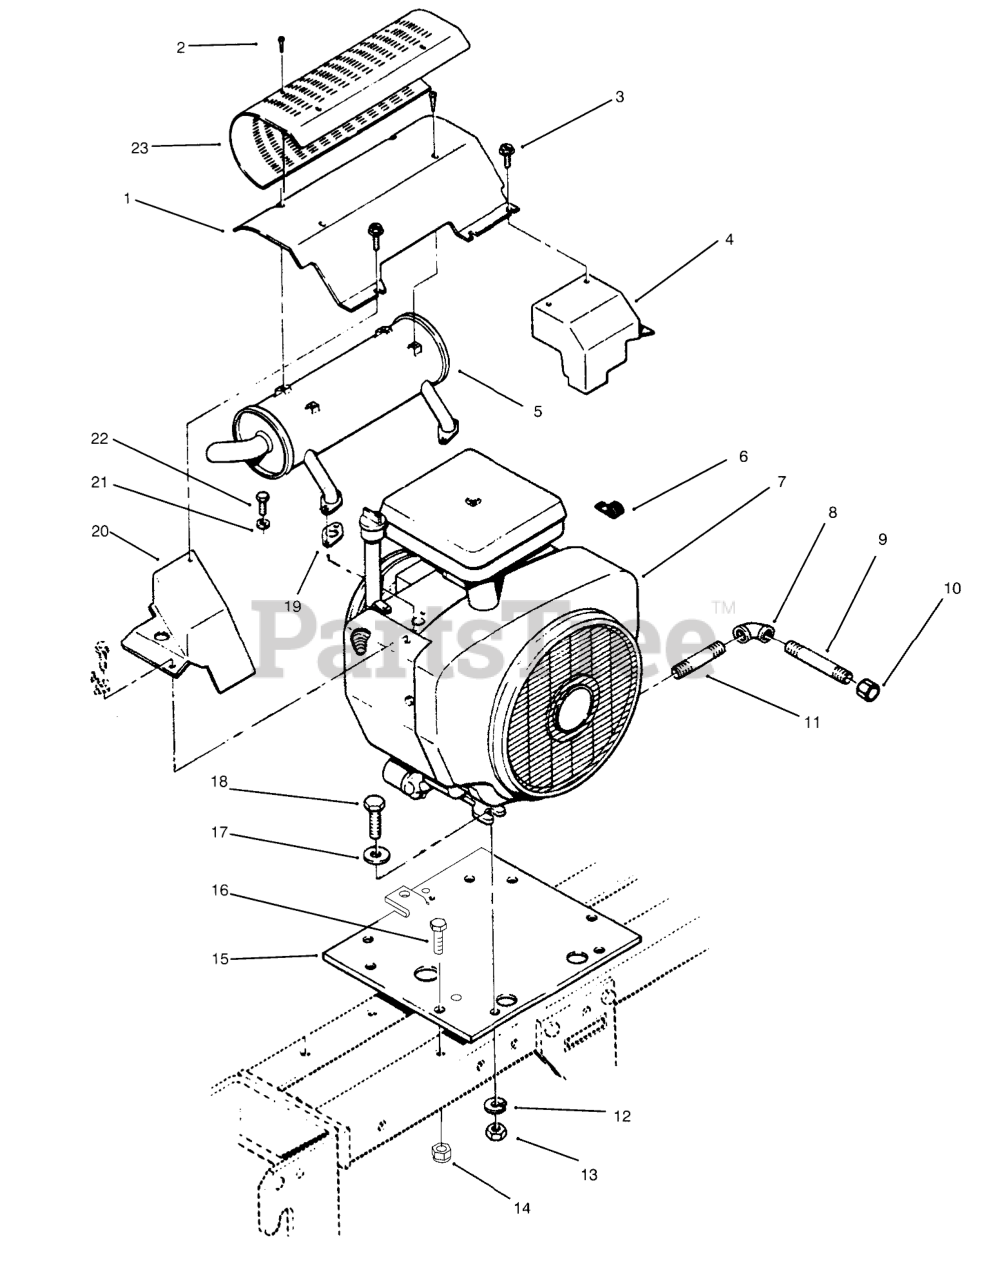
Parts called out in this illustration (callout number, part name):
1	Air Deflector
2	SCW 10-24 STAINLESS
3	SCREW
4	RH Exhaust Cover
5	MUFFLER-EXHAUST
6	CLIP
7	Engine-20HP
8	ELBOW 3/8 90 DEG
9	PIPE-NIPPLE 3/8 X 4"
10	CAP-PIPE
11	Pipe
12	WASHER-LOCK
13	NUT-HEX
14	NUT-LOCK, NI
15	PLATE-ENGINE B
16	SCREW-HH
17	WASHER-FLAT
18	SCREW-HH
19	GASKET
20	LH Exhaust Cover
21	WASHER-LOCK
22	SCREW-HH
23	SHIELD
